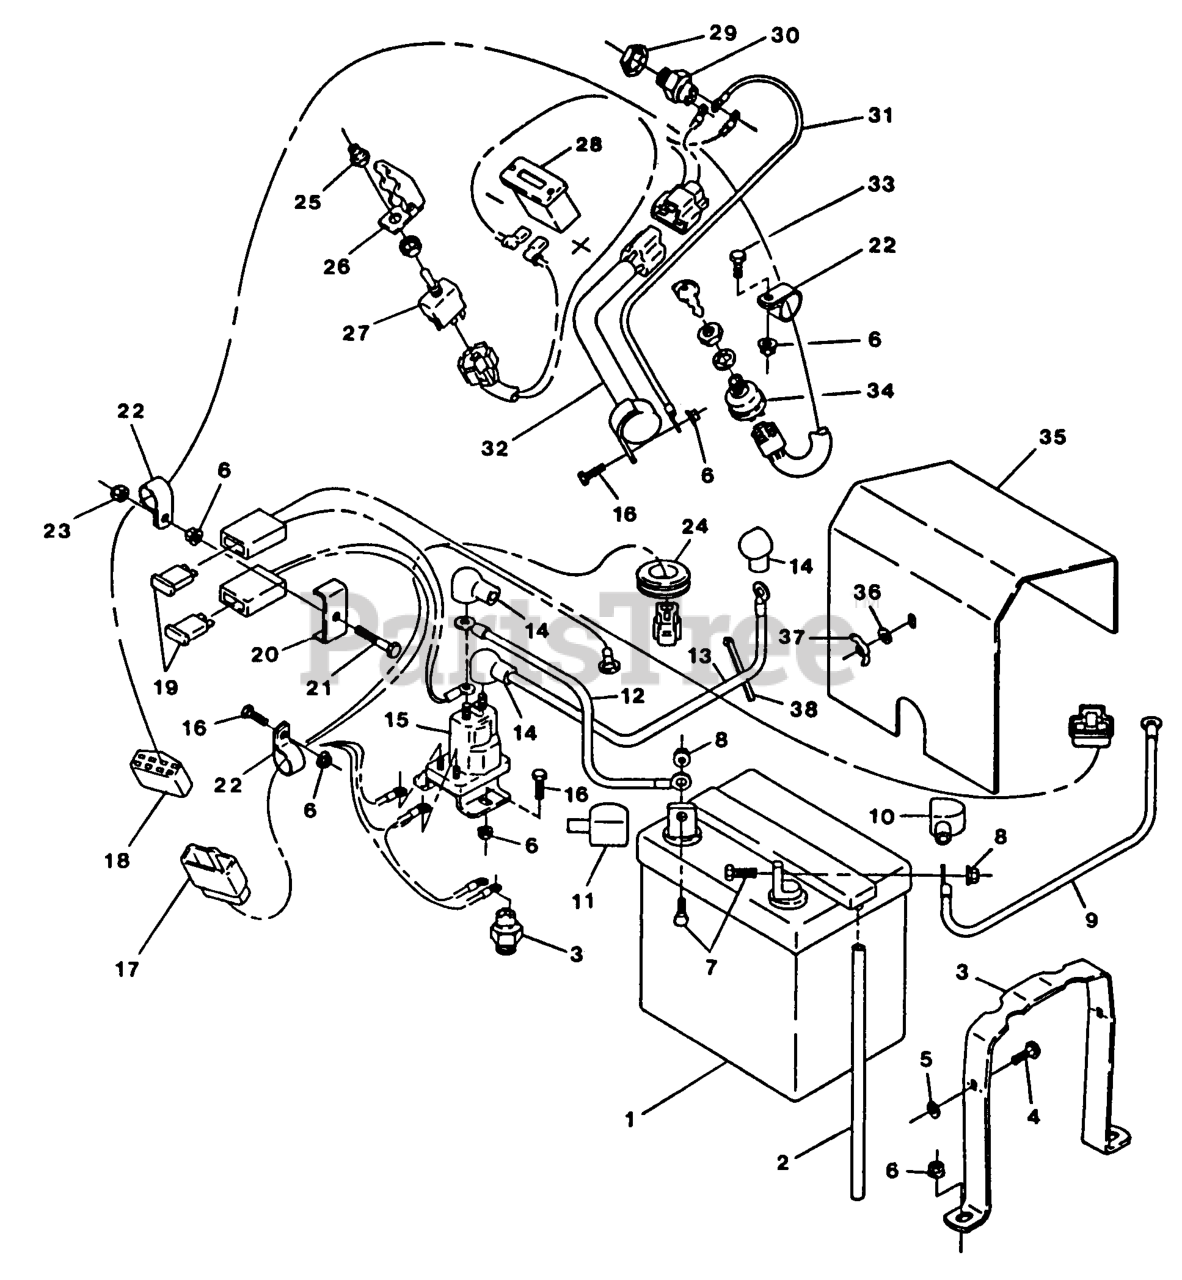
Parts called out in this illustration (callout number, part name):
1	Battery, 12v Manifold
4	BOLT-CARR
5	NUT-RETAINING
10	INSULATOR, BATTERY -
14	INSULATOR-SOLENOID
19	FUSE-BLADE TYPE, 20 AMP
20	CLIP-FUSE BLOCK PLTD
22	CLIP-LOOM
24	GROMMET
25	BOOT-SWITCH, TOGGLE
28	METER-HOUR
30	SWITCH,OPERATOR CNTRL
37	NUT-WING
38	TIE-CABLE
39	SWITCH-START, NEUTRAL
